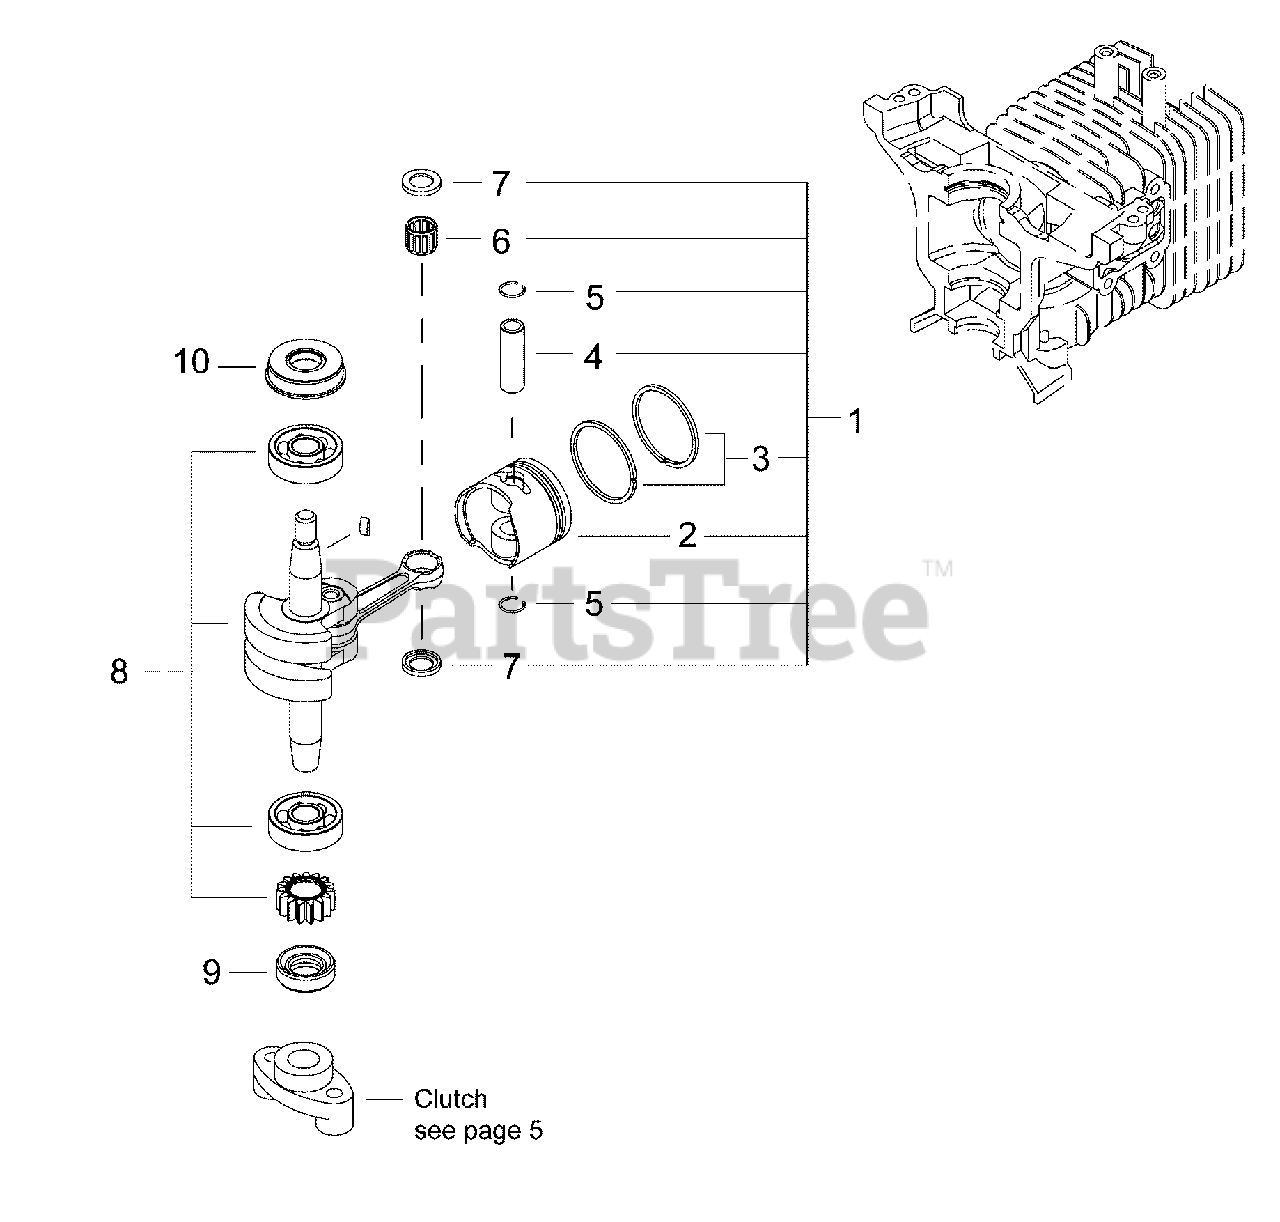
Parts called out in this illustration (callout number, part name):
1	PISTON KIT
2	PISTON
3	RING, PISTON
4	PIN, PISTON
5	RING, SNAP
6	BEARING, NEEDLE 9
7	WASHER, THRUST 9
8	CRANKSHAFT ASSY
9	SEAL, OIL 12
10	SEAL, OIL 12
